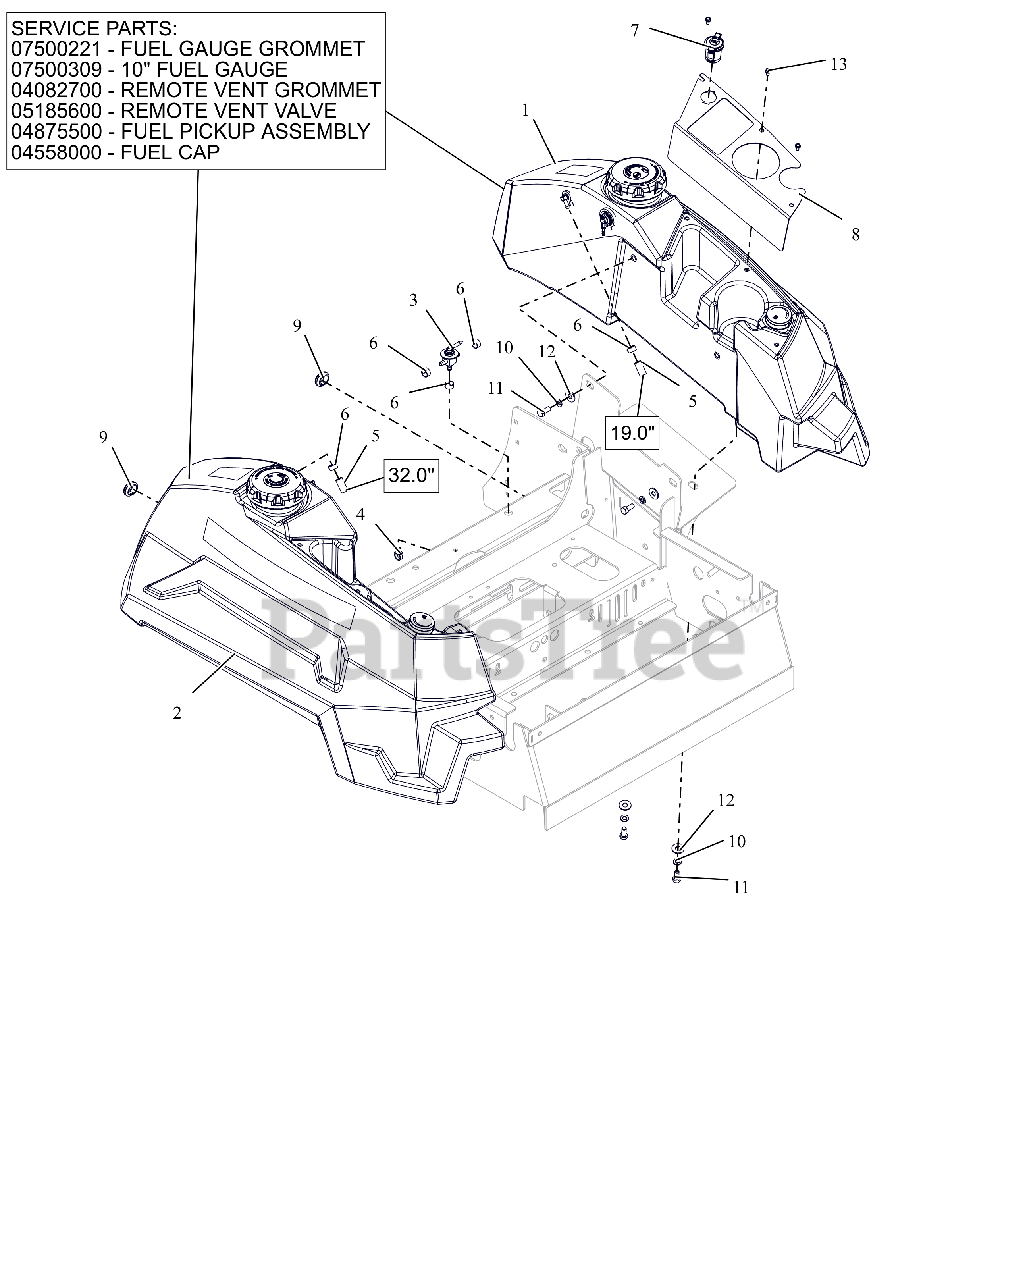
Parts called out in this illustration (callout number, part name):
1	ASM, LH FUEL TANK
1	GROMMET, FUEL GAUGE
1	GAUGE, REMOTE FUEL SEALED 10"
1	GROMMET, REMOTE VENT NITRILE
1	VALVE, COMBINATION VENT 3/16
1	ASSM,LRG TANK FUEL PICKUP LINE
1	CAP, FUEL VENTIN AUTOLOCK
2	ASSY-RH, PT400 FUEL TANK
3	VALVE - FUEL
4	ROUTING CLIP (1/2" ID)
5	HOSE, .25 LOW-PERM BULK GAS
6	CLAMP, FUEL LINE
7	PORT, 12 VOLT POWER
8	CUP HOLDER/POCKET PLATE - RED
9	GROMMET,RUBBER 5/8 ID/1.13 OD
10	WSHR,LK-REG .312X.078 ZCC
11	BLT,HEX .31-18X.75 G5 ZCC
12	WSHR,FLT .375X.875X.083 ZCC
13	SCR-MCH 10-24X.38 HWHSTAINLESS
